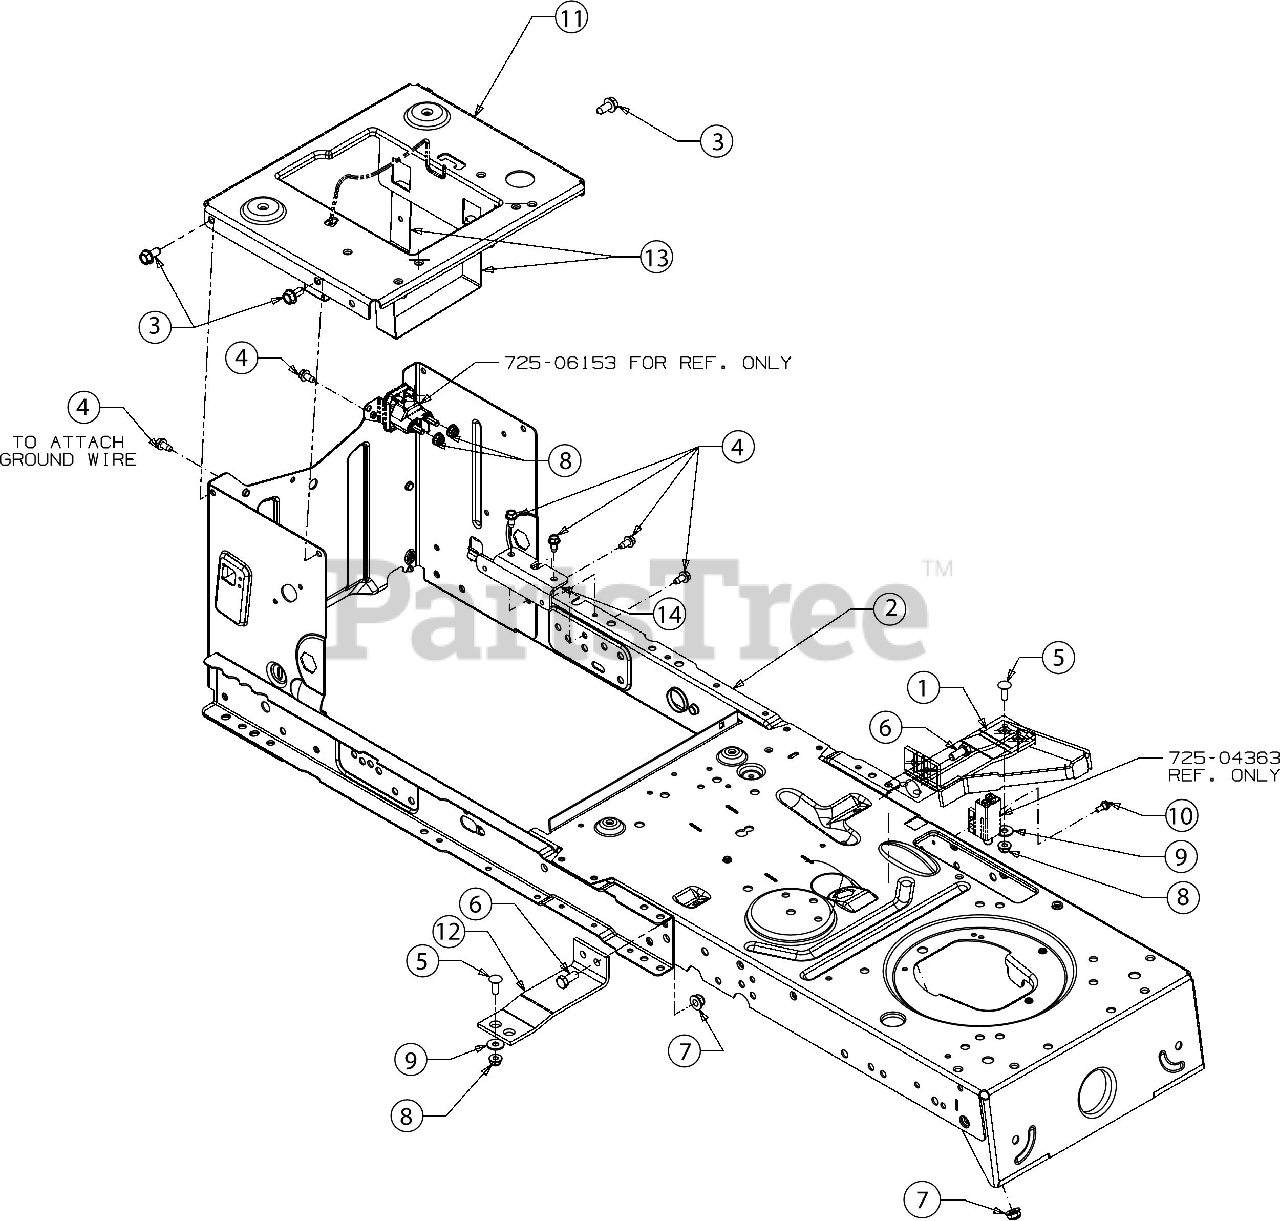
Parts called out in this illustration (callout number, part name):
1	RUNNINGBOARD BRACKET (LH)
2	FRAME ASSEMBLY
3	SCREW 5/16-18 X .750
4	SCREW 1/4-20 X.500
5	SCREW 1/4-20 X .75 GR5
6	SCREW 5/16-18 X .75 GR5
7	FLANGE LOCK NUT 5/16-18
8	FLANGE LOCK NUT
9	FLAT WASHER .28 ID X .74 OD X .063
10	SHOULDER SCREW
11	SEAT FRAME BRACKET
12	RUNNINGBOARD BRACKET (RH)
13	BATTERY BRACKET
